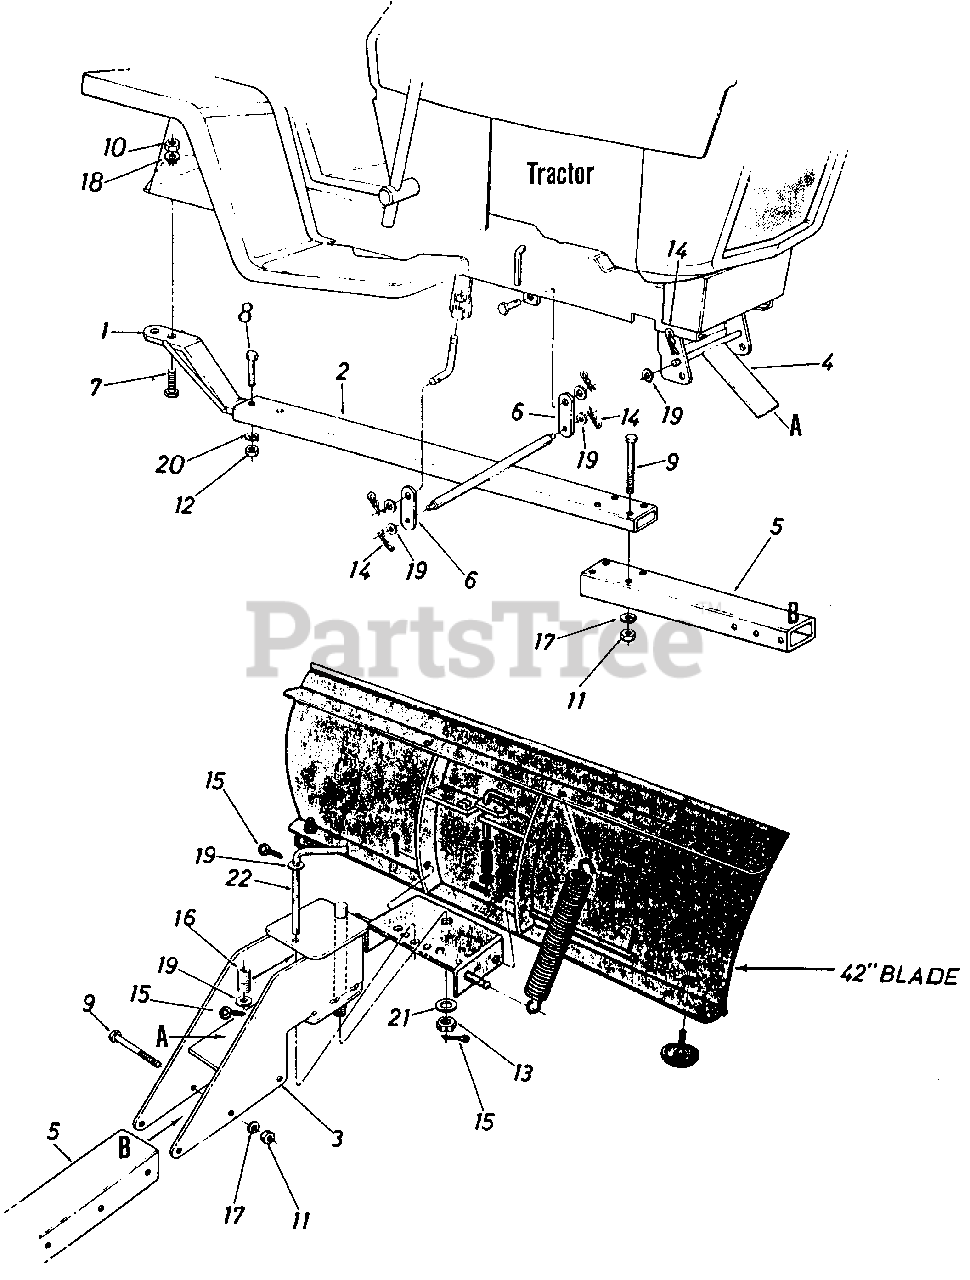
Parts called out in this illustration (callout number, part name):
1	BRACKET ASSY., HANGING
2	SHAFT ASSY, LIFT
3	BRACKET ASSY, PIVOT
4	PLATE ASSY, GUIDE
5	TUBING, RECTANGULAR
6	LINKAGE, LIFT
7	BOLT, 5/8-18 X 1.31 IN.
8	BOLT, 1/2-20 X 1.50 IN.
9	BOLT, 3/8-24 X 3.75 IN.
10	NUT, 5/8-18 LOCK
11	NUT, 3/8-24
12	NUT, 1/2-13 JAM
13	NUT, 3/4-16 GR 5 CASTLE
14	PIN, 1/2 INT COT
15	PIN, 5/32 X 1-1/4 COT
16	SPRING, COMPRESSION
17	WASHER, 3/8 LOCK
18	WASHER, .64 X 1-1/4 IN.
19	WASHER, .510 X 1.0 X .06
20	WASHER, 1/2 LOCK
21	WASHER, .812 X 1.469 IN.
22	BRACKET, HANDLE PIVOT
